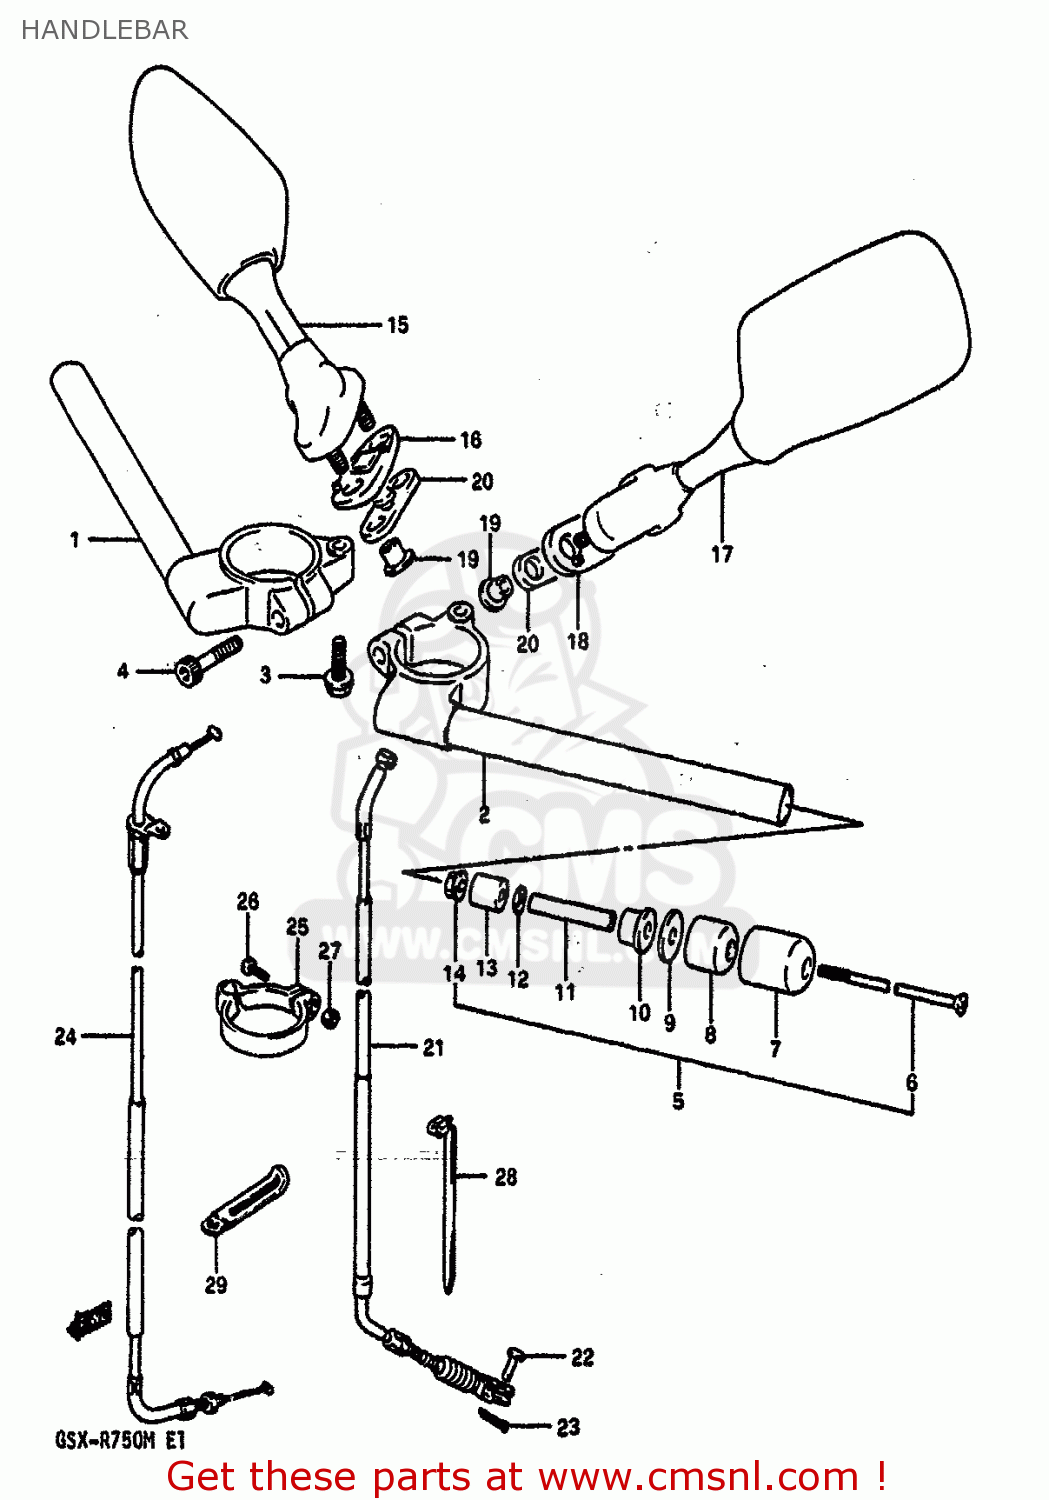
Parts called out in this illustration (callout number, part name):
1	HANDLEBAR,R
2	HANDLEBAR,L
3	BOLT 6X20
4	BOLT 8X35
5	BALANCER SET,HANDLEBAR
6	SCREW(6X127)
7	CAP,BALANCER
8	BALANCER,HANDLEBAR
9	SPACER,BALANCER
10	EXPANDER,HANDLE BALANCER
11	SPACER,EXPANDER
12	WASHER
13	EXPANDER,HANDLE BALANCER
14	NUT
15	MIRROR ASSEMBLY,REAR VIEW
16	GASKET,RR VIEW MIRROR,R (NAS)
17	MIRROR ASSEMBLY,REAR VIEW
18	GASKET,RR VIEW MIRROR,L (NAS)
19	NUT,RR VIEW MIRROR
20	CUSHION,RR VIEW MIRRORR
21	CABLE ASSY,CLUTCH
22	PIN(L:15)
23	PIN
24	CABLE ASSY,THROTTLE
25	CLAMP,CLUTCH CABLE
26	SCREW
27	NUT ,5MM
28	CLAMP(L:235)
29	CLAMP
